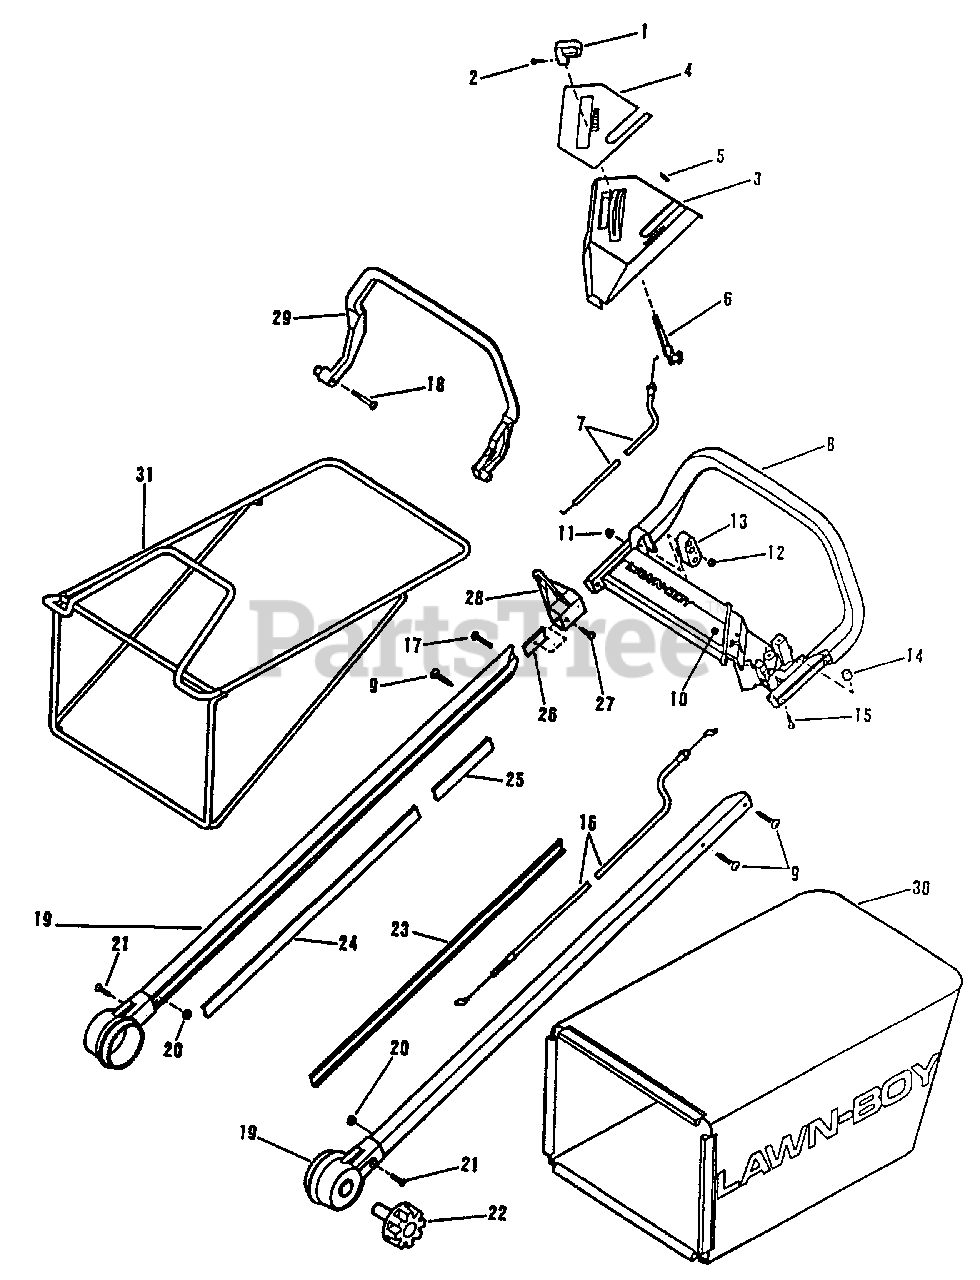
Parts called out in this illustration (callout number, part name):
1	Throttle Knob Assembly
2	Set Screw
3	Upper Cover Assy (ZPRA)
4	Plate
5	Plug
6	Throttle Lever
7	Throttle Cable Assembly
8	Handle and Decal Assy (ZPRA)
9	Thread Forming Screw
10	Decal-Lawn-Boy
11	Locknut
12	Locknut
13	Bail Block
14	Bumper
15	Screw-Cover to Handle
16	Engine Brake Cable Assembly
17	Screw-Extrusion & Block to Handle
18	Screw-Bail Pivot
19	Knuckle and Extrusion
20	Nut
21	Screw
22	Handle Adjustment Knob
23	Handle Insert-Cable Side
24	Handle Insert-Below Guide
25	Handle Insert-Above Guide
26	Nut Plate
27	Screw-Rope Guide to Handle
28	Rope Guide
29	Engine Brake Bail
30	Rear Grass Bag
31	Catcher Bag Frame
